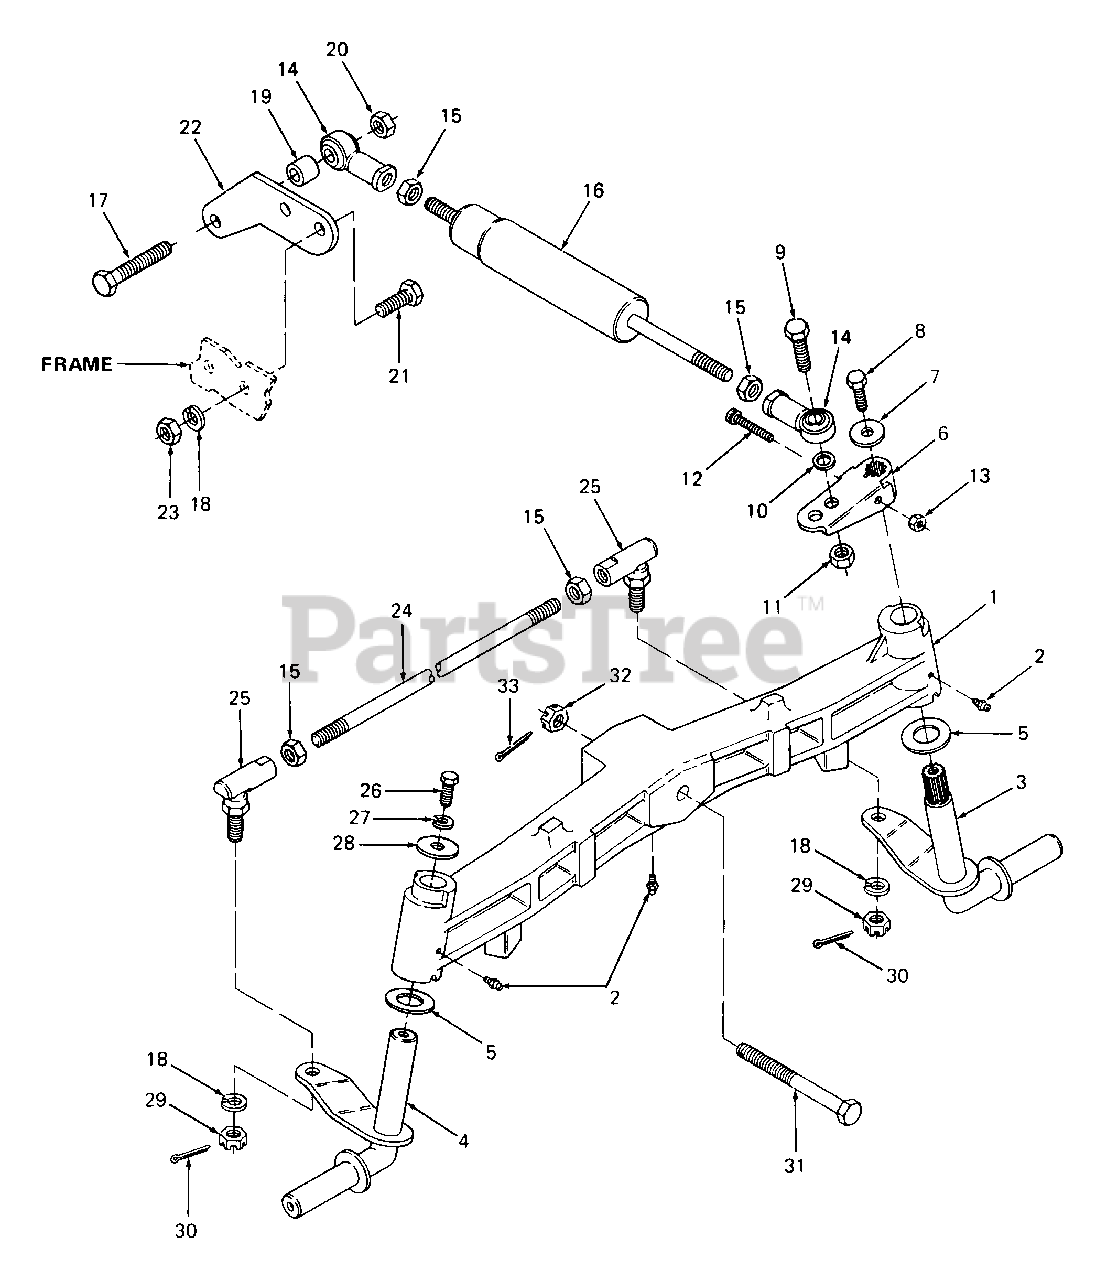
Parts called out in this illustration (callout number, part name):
3	Knuckle, Steering - LH
4	Knuckle, Steering - RH
5	Washer, Thrust, 1.03 x 1.62 x .03 Thk HDN
8	Bolt, Hex Patch, 3/8-16 x 1.0 Lg GR5
9	Bolt, Hex, 1/2-20 x 1.5 Lg GR5
10	Washer, Flat, .531 x .688 x .054 Thk
11	Nut, Hex Top Lock, 1/2-20
12	Screw, Socket Hd Cap, 1/4-20 x 2.0 Lg
13	Nut, Hex Patch Lock, 1/4-20
14	Alignaball End, 1/2-20
15	Nut, Hex Jam, 1/2-20 GR5
18	Washer, Lock, 1/2
19	Spacer, .505 x .75 x .780 Lg
20	Nut, Hex Center Lock, 1/2-13 GR5
21	Screw, Hex Cap, 1/2-13 x 1.25 Lg GR5
22	Bracket, Power Steering Mtg
23	Nut, Hex, 1/2-13 GR5
25	Ball Joint
26	Screw, Hex Cap, 3/8-16 x 1.0 Lg GR5
27	Washer, Lock, 3/8
28	Washer, Flat, .406 x 1.5 x .12 Thk
29	Nut, Hex Castle, 1/2-20 GR5
30	Pin, Cotter, 3/32 Dia x 1.25 Lg
31	Bolt, Hex, 3/4-10 x 5.25 Lg GR5
32	Nut, Hex Castle, 3/4-10
33	Pin, Cotter, 1/8 Dia x 1.5 Lg
